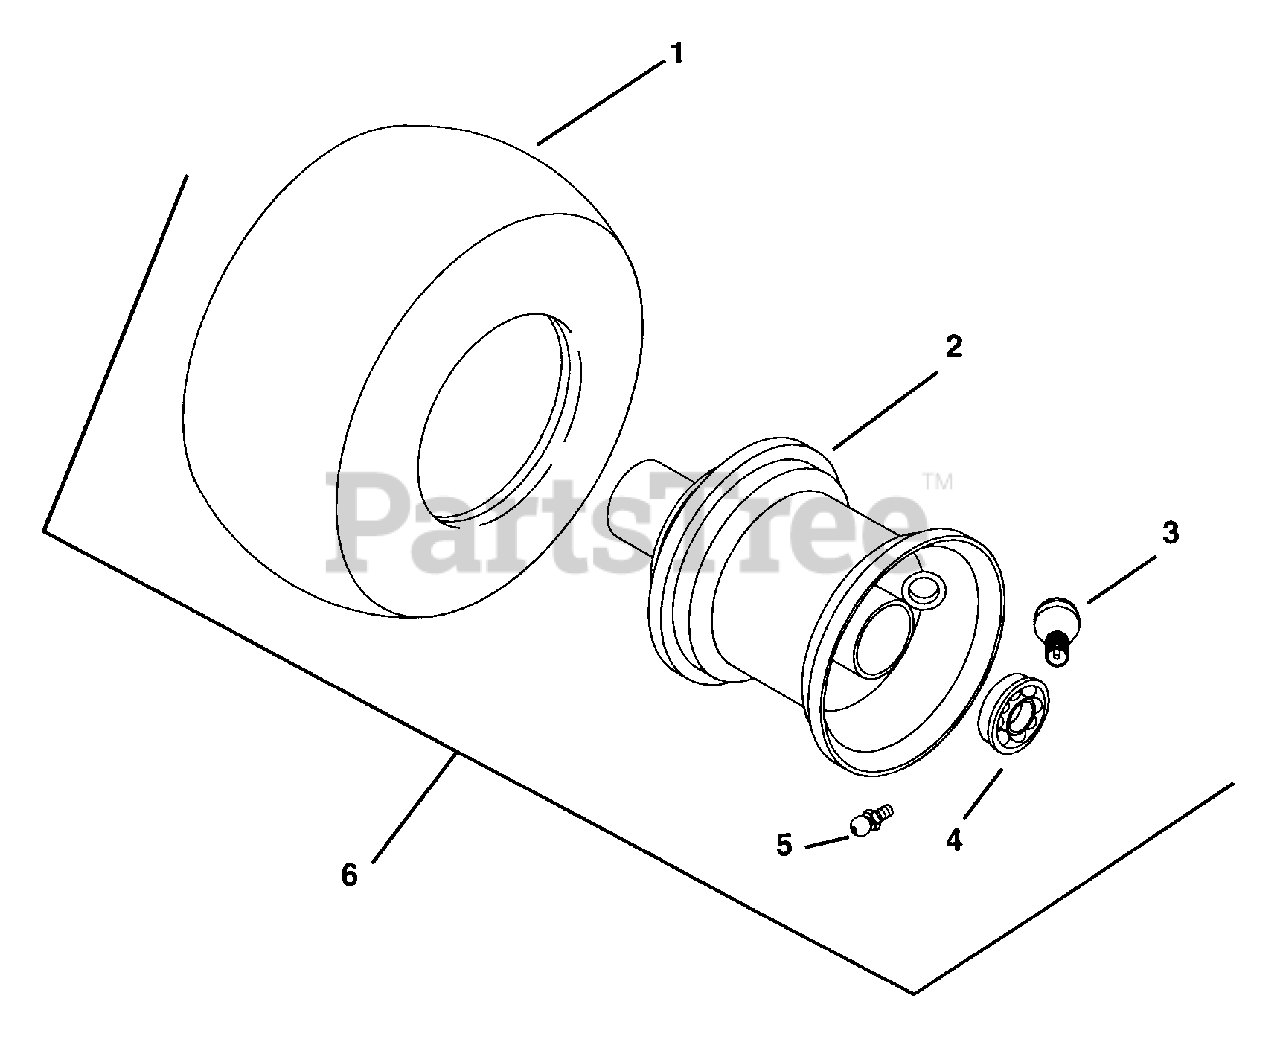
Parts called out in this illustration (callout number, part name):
1	TIRE, 13X6.5-6
2	RIM ASSEMBLY
3	VALVE STEM ASS'Y
4	RADIAL BEARING
5	FTG-LUBE .25-28X.256 YWZC
6	TIRE/WHEEL ASSY, 13X6.50-6
